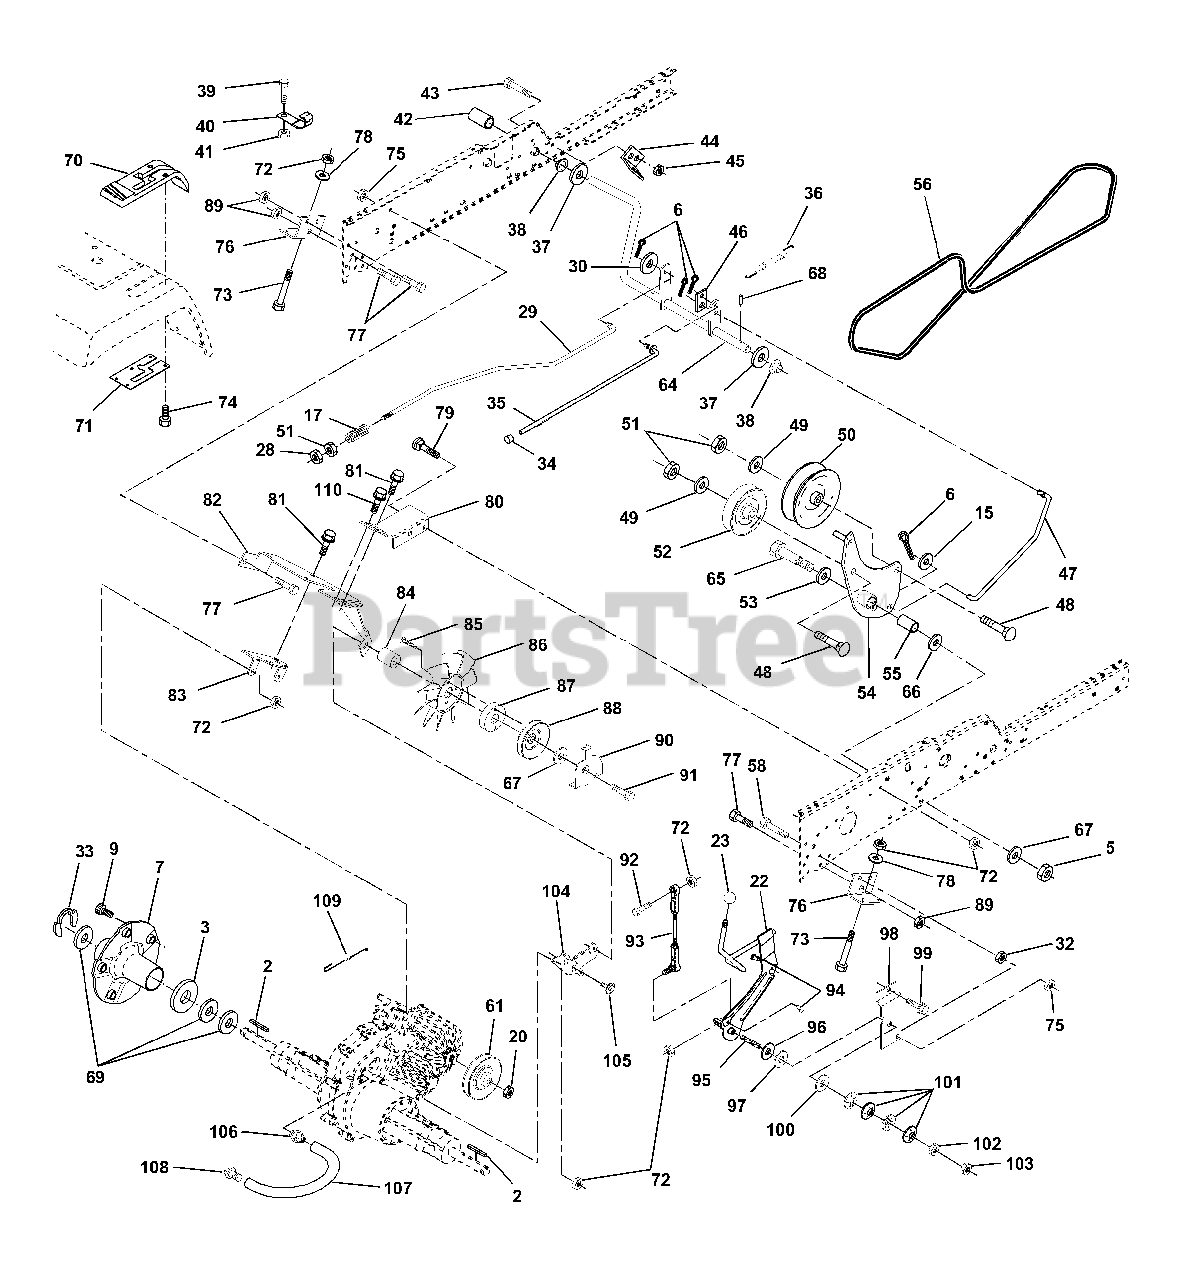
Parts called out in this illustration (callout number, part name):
2	Key 1/4 x 2.5
3	Washer Thrust Axle Harden
5	Nut Crownlock 3/8-16
6	Pin Cotter 1/8 x 3/4
7	Wheel Hub Asm.
15	Washer 13/32 x 13/16 x 16 Ga.
17	Spring Rod Brake
20	Nut Hex Jam Toplock 1/2-20
22	Shaft Arm Asm
28	Nut, Hex Jam 3/8-16
30	Washer 13/32 x 1 x 16Ga
32	Nut Hex 7/16-14
34	Cap Plunger
35	Rod Parking Brake
36	Spring Extension
37	Washer 25/32 x 1-1/4 x 16 Ga.
39	Screw Fin #10-24 x 1
40	Actuator Interlock Switch
41	Nut Lock #10-24
42	Cover Pedal
43	Bolt Hex Head 1/4-20 x 3/4
44	Bracket Interlock
45	Nut Lock W/Insert 1/4-20
46	Retainer Spring
47	Clutch Rod
48	Bolt Carriage 3/8-16 x 1-3/4 Gr. 5
49	Washer 13/32 x 7/8 x 13 Ga
50	Pulley Idler Flat
51	Nut Lock Hex 3/8-16
52	Pulley Idler Grooved
53	Washer Hartdened
54	Clutch Arm Asm
55	Bearing, Idler
58	Bolt Fin Hex 7/16-14 x 1-1/2
61	Pullery Transaxle
64	Shaft Asm Brake Parking Clutch
65	Bolt Shoulder
66	Washer Hardened
67	Washer 13/32 x 13/16 x 12 Ga
70	Console Hydro Fender
71	Plate Console Shift
72	Locknut Hex W/Washer Insert
73	Bolt Fin Hex 5/16-18 x 3
74	Screw, Hex Wsh Hi-Lo 1/4-1/2
75	Nut Lock Hex 7/16
76	Bracket Transaxle
77	Bolt Fin Hex 7/16-14 x 1
78	Washer 11/32 x 3/4 x 12 Ga.
79	Bolt Carriage 5/16-18 x 5/8
80	Bracket Torque RH
81	Screw Thdrol 3/8-16 x 3/4
82	Bracket Mount Torque/Fan
83	Strap Torque Mid
85	Screw #10-24 x 1-1/4
86	Fan 7" Hydro
87	Adapter Fan
88	Pulley Idler
89	Nut, Crownlock 7/16-14
90	Keeper Belt
91	Screw Thdrol 3/8-16 x 2-3/4
92	Bolt Fin Hex 5/16-18 x 1.75
93	Link Shift Asm
94	Fastner Christmas Tree
95	Screw Set 5/16-18 x 1.75
96	Washer Nickel Plated
97	Bearing Trust
98	Bracket Shift
99	Screw Thdrol 3/8-16 x 1-1/2
100	Washer Compression
101	Washer Bellville
102	Nut Hex Nylok
103	Nut Hex Jam 5/16-18
104	Bracket Idler
105	Screw Tap 1/4-20 x 1/2
106	Fitting Vent Hose
109	Spring Return Brake
110	Screw, Hinge
